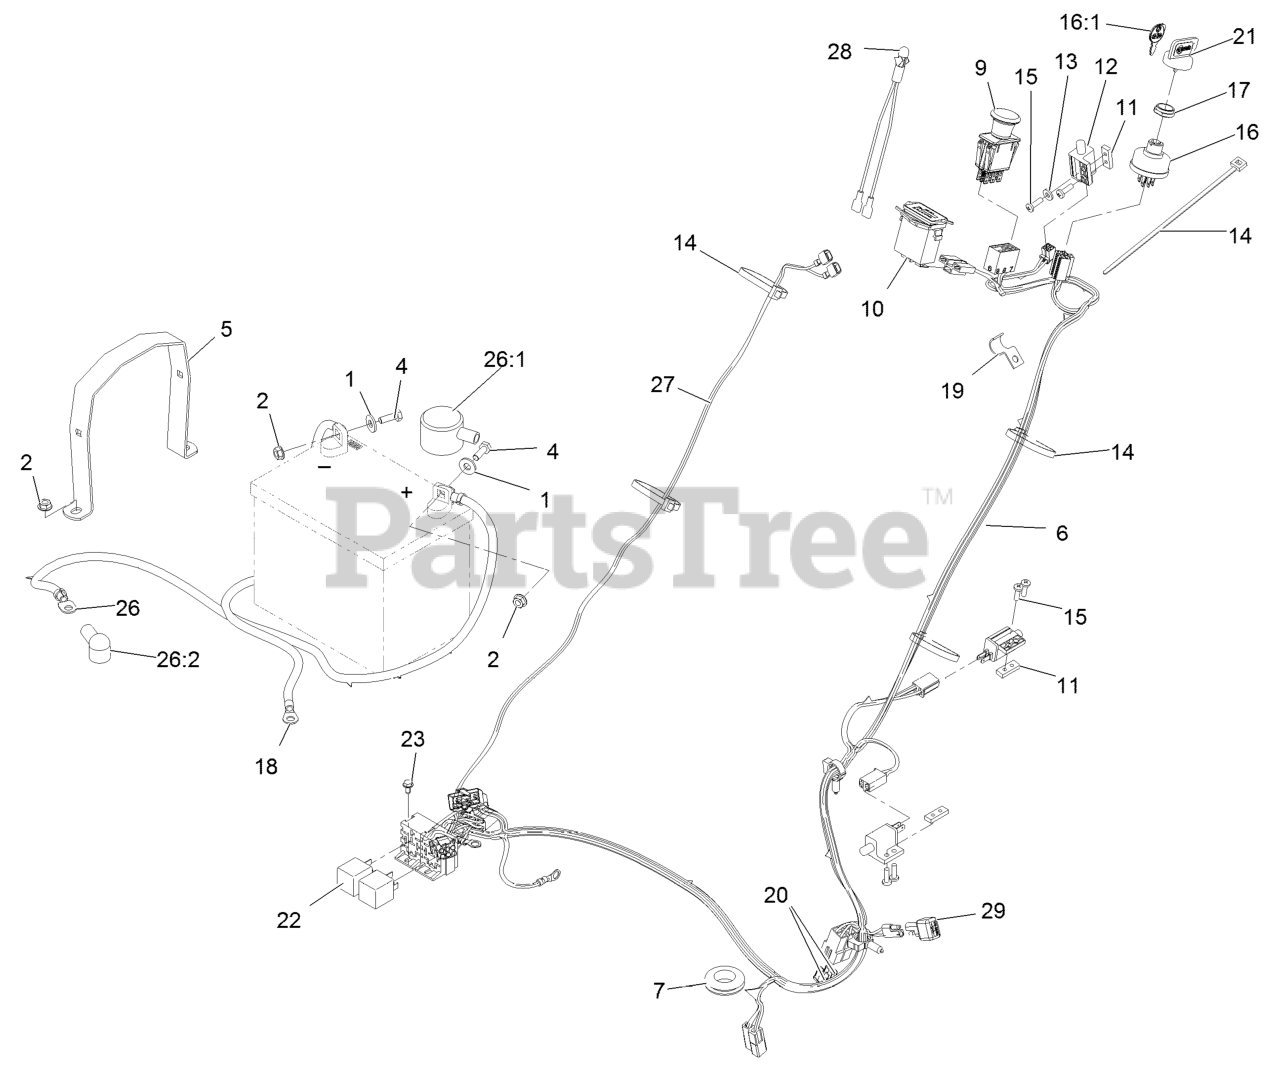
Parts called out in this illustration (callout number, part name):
1	WASHER-FLAT
4	SCREW-HH
5	STRAP,BATTERY HOLDDOWN
6	HARNESS-WIRE, TTX
7	GROMMET
9	SWITCH-PTO
10	METER-HOUR
11	PLATE-TAPPED
12	SWITCH-OPEN, NORMALLY
13	WASHER-FLAT
14	TIE-PLASTIC
15	SCREW-PPH
16:1	KEYS-IGNITION (SPARE PAIR
17	NUT-SWITCH, IGNITION
18	WIRE-GROUND
19	CLIP-HALF, LOOM
20	FUSE-BLADE TYPE, 20 AMP
21	KEY-IGNITION
23	SCREW-HWH
26	POSITIVE BATTERY CABLE AS
26:1	INSULATOR-BATTERY
26:2	INSULATOR-SOLENOID
27	HARNESS, MIL
28	INDICATOR-LED, RED
